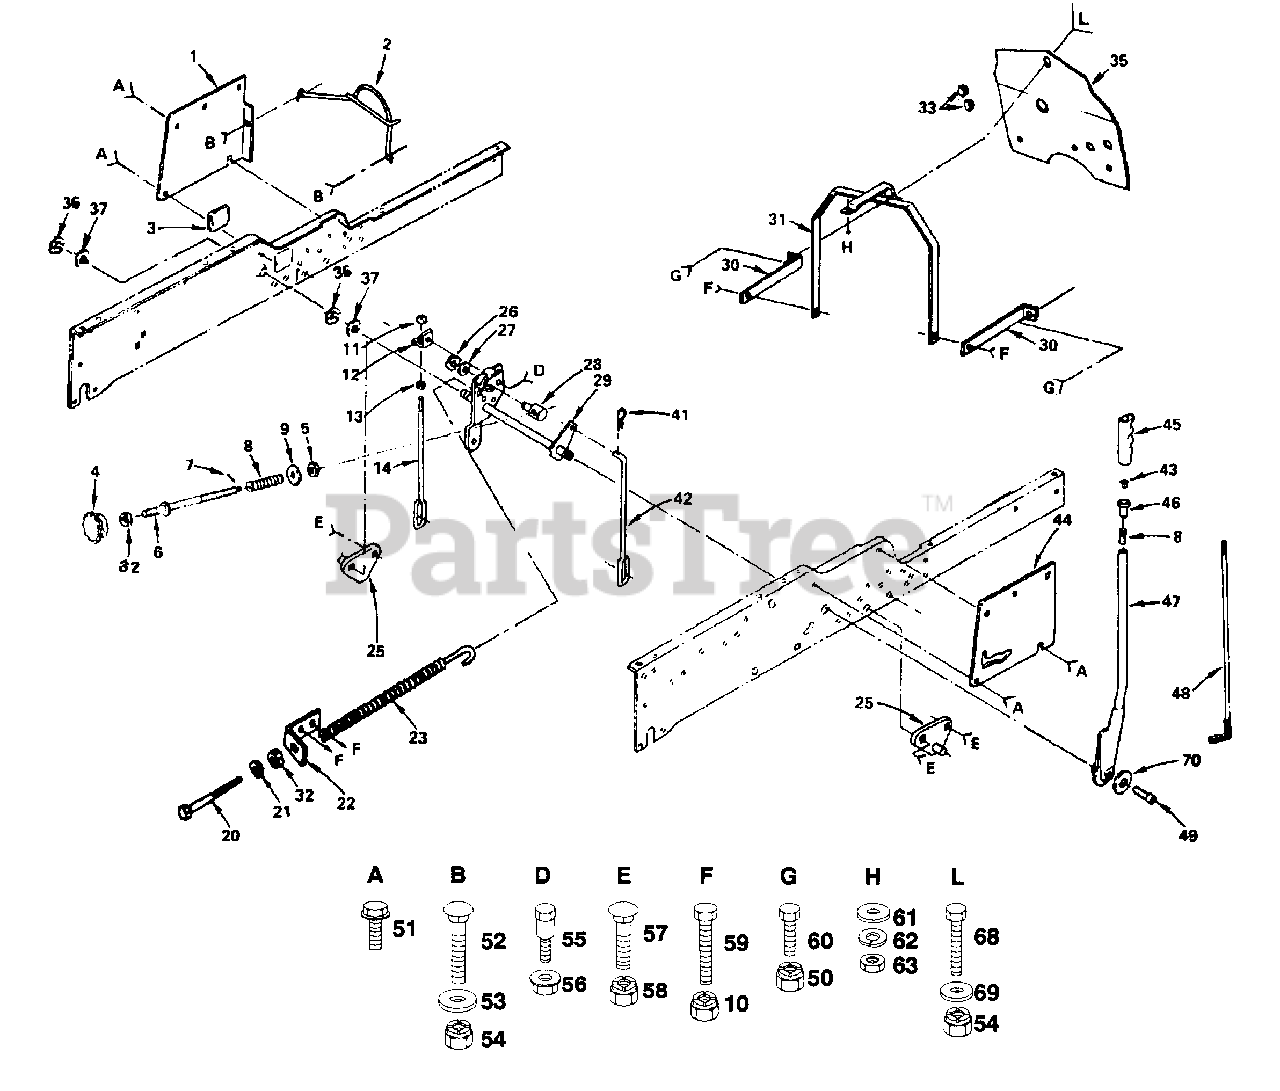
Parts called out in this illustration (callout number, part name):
1	Panel, Side, L.H. (AYP part number)
2	Guard Assembly, Belt, Engine (AYP part number)
3	Cover, Access (AYP part number)
4	Handle, Adjust, Lift (AYP part number)
5	Nut (AYP part number)
6	Rod, Adjust, Lift (AYP part number)
7	Pin, Cotter (AYP part number)
8	Spring (AYP part number)
9	Washer 13/32 x 5/8 x 16 Gauge (AYP part number)
10	Nut, Crownlock 3/8-16
11	Locknut, Hex w/Washer 3/8-16 (AYP part number)
12	Bracket, Lift, L.H. (AYP part number)
13	Nut, Hex 3/8-16 (AYP part number)
14	Link, Lift, L.H. (AYP part number)
20	Bolt, Adjust, Spring, Assist (AYP part number)
21	Washer 13/32 x 13/16 x 16 Ga. (AYP part number)
22	Bracket, Spring, Assist (AYP part number)
23	Spring Assembly, Assist, Lift (AYP part number)
25	Bracket, Suspension (AYP part number)
26	Ring, Klip (AYP part number)
27	Washer 15/32 x 3/4 x 16 Gauge (AYP part number)
28	Trunnion, Stop Depth
29	Shaft, Lift (AYP part number)
30	Bracket, Shield, Heat, Side (AYP part number)
31	Assembly, Support, Dash
32	Nut, Hex Jam 3/8-16 (AYP part number)
33	Grommet (AYP part number)
35	Base, Shield, Heat (AYP part number)
36	Klip, Ring (AYP part number)
37	Washer 29/32 x 1-1/4 x 16 Gauge (AYP part number)
41	Retainer, Spring (AYP part number)
42	Link, Lift, R.H. (AYP part number)
43	Button, Plunger (AYP part number)
44	Panel, Side, R.H. (AYP part number)
45	Grip, Handle (AYP part number)
46	Plunger, Lever, Lift (AYP part number)
47	Lever Assembly, Lift (AYP part number)
48	Rod Assembly, Lever (AYP part number)
49	Bolt, Hex 3/8-16 x 1-1/2 (AYP part number)
50	Nut, Crownlock 1/4-20 (AYP part number)
51	Screw, Hex Washer Thd. 3/8-16 x 1/2 (AYP part number)
52	Bolt, Carriage 5/16-18 x 1 (AYP part number)
53	Washer 11/32 x 1 x 10 Ga. (AYP part number)
54	Nut, Crownlock 5/16-18
55	Bolt, Shoulder (AYP part number)
56	Nut, Hex Flange 1/4-20
57	Bolt, Carriage 3/8-16 x 3/4 (AYP part number)
58	Nut, Centerlock 3/8-16 (AYP part number)
59	Bolt, Hex 3/8-16 x 1 (AYP part number)
60	Bolt, Hex 1/4-20 x 1/2 (AYP part number)
61	Washer 9/32 x 3/4 x 16 Ga. (AYP part number)
62	Washer, Lock 1/4 (AYP part number)
63	Nut, Hex 1/4-20 (AYP part number)
68	Bolt, Hex 5/16-18 x 3/4 (AYP part number)
69	Washer 11/32 x 3/4 x 16 Gauge (AYP part number)
70	Washer, Lock 3/8 (AYP part number)
